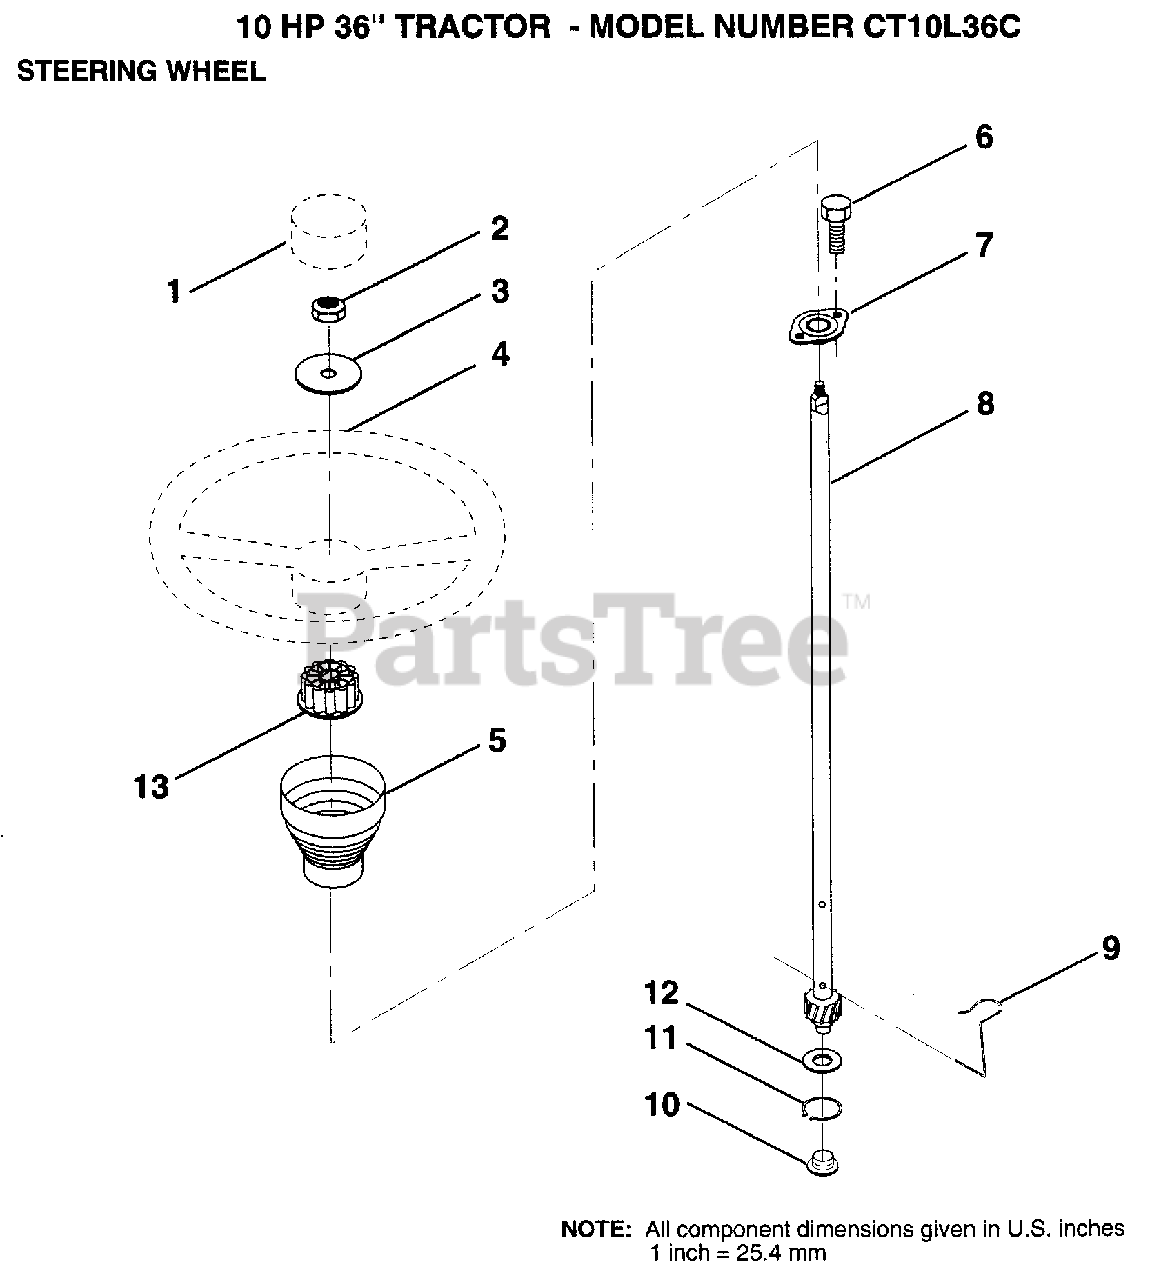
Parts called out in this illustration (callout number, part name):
2	GRIPCO NUT
3	WASHER T
5	SLEEVE STEERING
9	STEERING CLIP
10	BUSHING STEER LWR
11	RING
12	WASHER LT
13	ADAPTER-WHEEL LT
